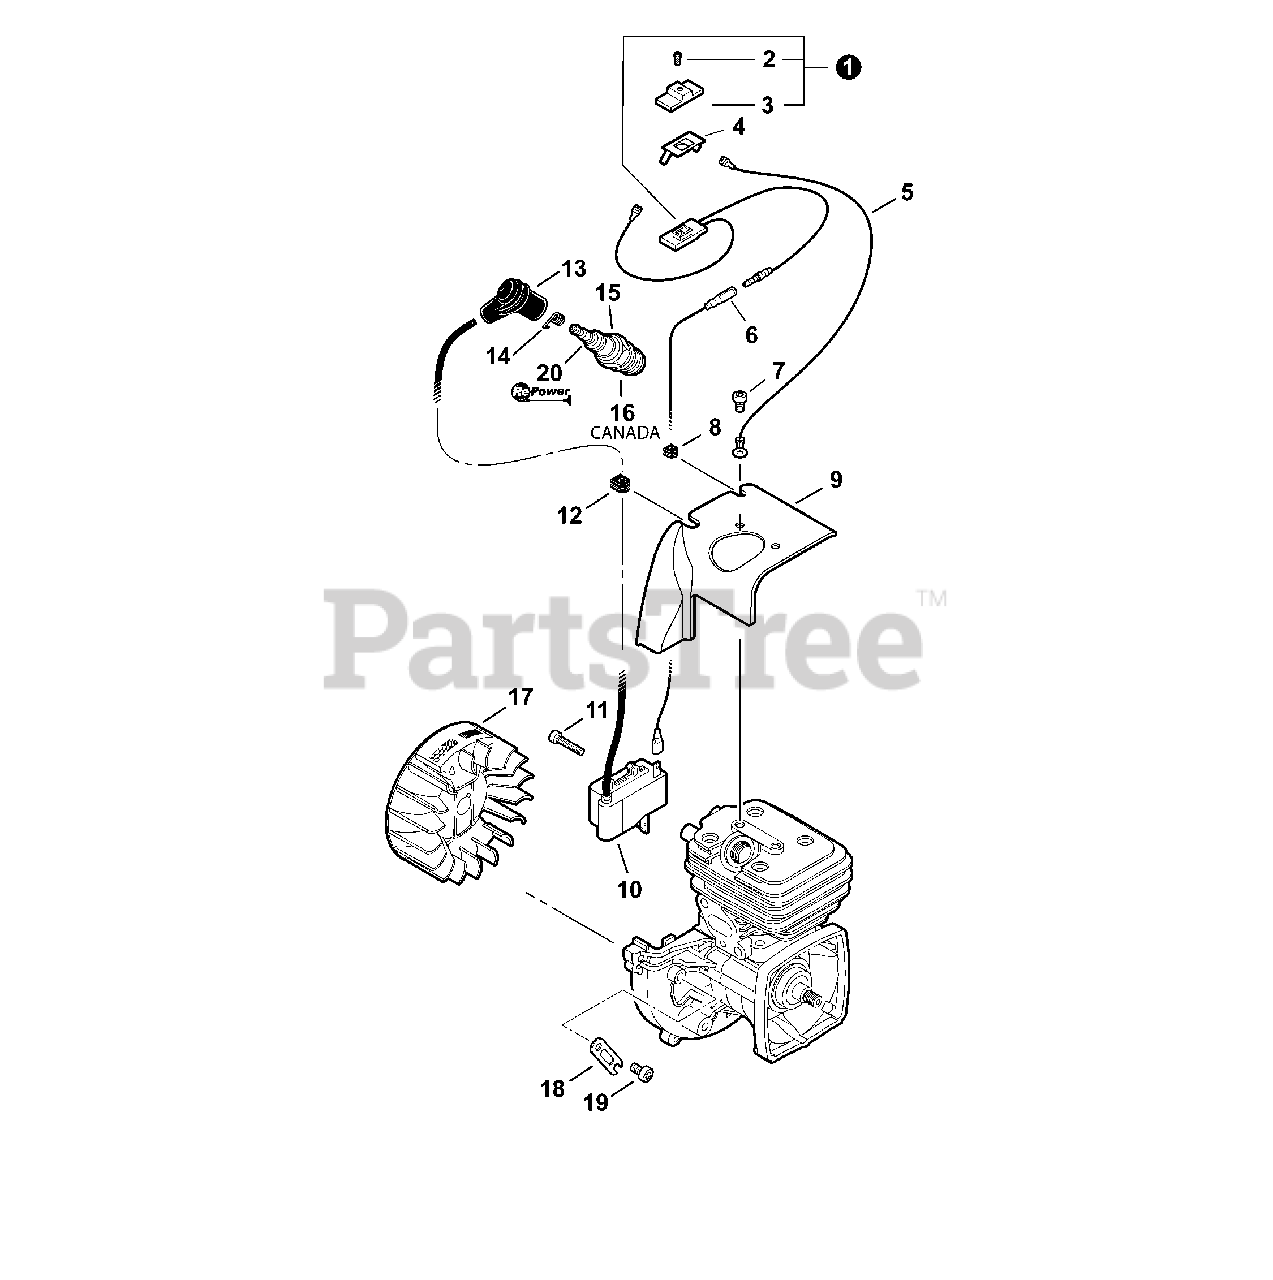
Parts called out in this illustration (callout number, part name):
1	SWITCH, IGNITION
2	SCREW - 3×10
3	KNOB, SWITCH - ORANGE
4	TERMINAL, LEAD
6	LEAD - IGNITION
7	SCREW - 5×8 -- TORX
9	SHIELD, CYLINDER
10	COIL, IGNITION
11	SCREW - 4×20 -- TORX
13	CAP, SPARK PLUG
14	TERMINAL, SPARK PLUG CAP
15	SPARK PLUG -- BPM8Y
16	SPARK PLUG -- BPMR8Y
17	FLYWHEEL
19	SCREW - 5×8 -- TORX
20	RePower TUNE-UP KIT
